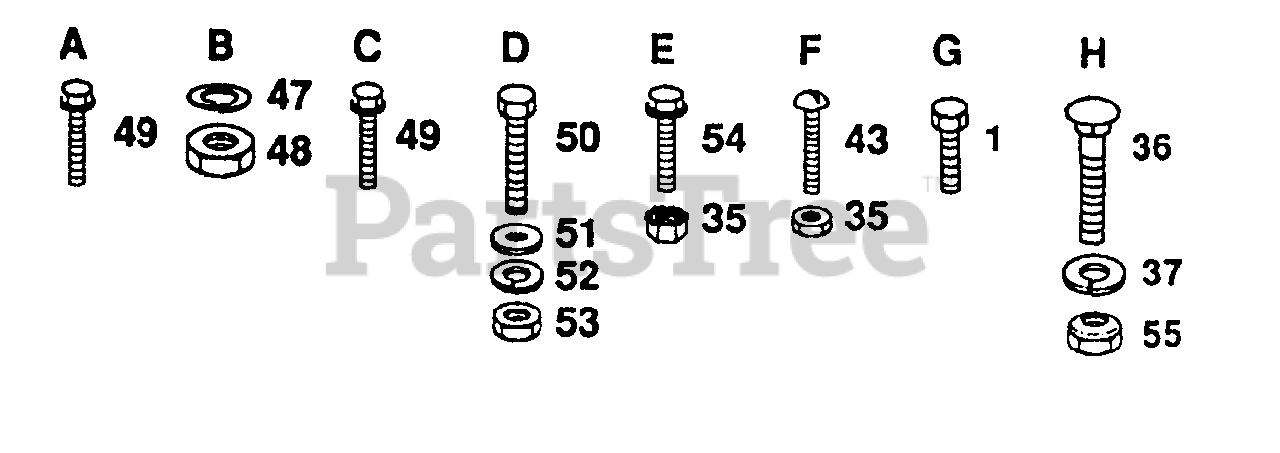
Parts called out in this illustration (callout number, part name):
1	Screw 10 - 24 x 1/2
35	Nut - Keps No. 10 - 32
36	Bolt, Carriage 3/8 -16 x 1
37	Washer, Lock 3/8
43	Screw-Slot-Pan HD 10 - 32 x 1/2
47	Lockwasher 1/4
48	Nut, Hex Jam 1/4 - 20
49	Screw - Hex Washer Hd. Cutting 1/4-20 x 1/2
50	Bolt - Hex Hd. 1/4 - 20 x 3/4
51	Washer 9/32 x 5/8 x 16 Ga.
52	Lockwasher 1/4
53	Nut-Hex 1/4 - 20
54	Screw- Hex Washer Hd. No. 10-32 x 1 - 1/2
55	Nut, Fin Hex 3/8 -16
